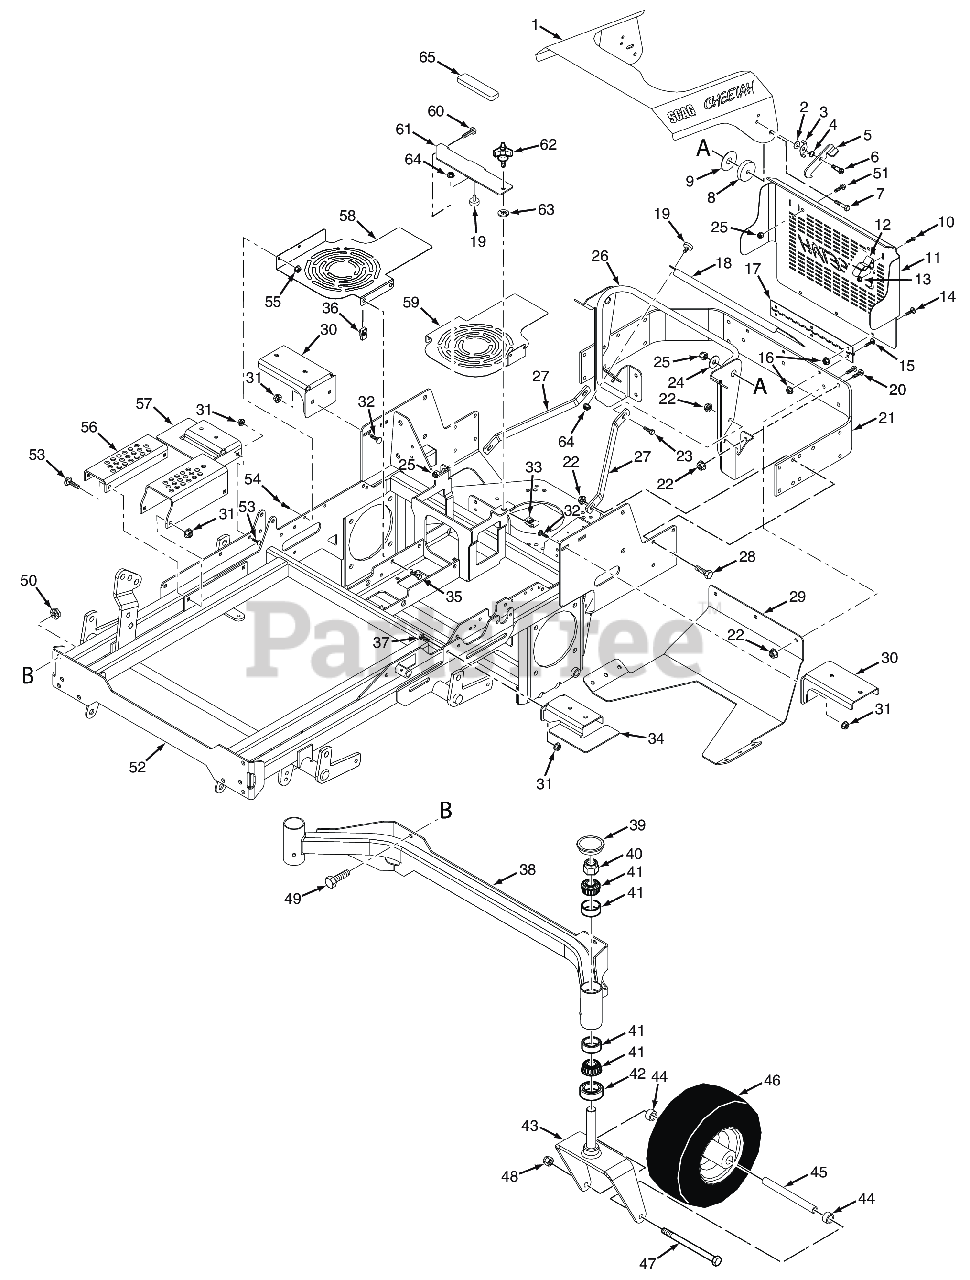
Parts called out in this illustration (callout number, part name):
1	Hood Assembly w/Decals
1	Hood Assembly w/Decals - Kohler ECV860
1	REPLACED BY 462721
2	Flatwasher, 3/8 (.406 x .812 x .065)
3	Lock, Hood Latch
4	Spring, Hood Latch
5	Latch, Hood
6	Bolt, Shoulder 5/16-18 x 1/2"
7	Bolt, Hex Head 3/8-16 x 1-3/4" (Kohler EFI)
8	Spacer, Hood
9	Disc, Anti-Friction
10	Screw, #8-32 x 1/2"
11	Belt Guard, Rear
11	Belt Guard, Rear - Kohler
12	Spring Clip
13	Nut, Elastic Stop #8-32
14	Bolt, Carriage 1/4-20 x 1/2"
15	Serr. Fl. Hex Head CPSCR, 1/4-20 x 3/4"
16	NUT, 1/4-20 SERRATED FLANGE HEX HEAD
17	Hinge, Belt Cover
18	ROPS Heatshield - Kohler
18	ROPS Heatshield - Briggs & Stratton
19	Bumper, Rubber 5/16-18 x 5/8"
20	Button Head Capscrew, Torx 3/8-16 x 1"
21	BUMPER, REAR - SCZ
22	NUT, 3/8-16 SERRATED FLANGE HEX HEAD
23	Bolt, Hex Head, 3/8-16 x 1 Gr. 5
24	Flatwasher, 3/8-.406 x 1-1-1/2 x 7 Gauge
25	HEX NUT, ELASTIC STOP LOCK, 3/8-16
26	Mount Weldment, Hood
26	Mount Weldment, Hood - Kohler
27	Brace, Hood Support
28	Bolt, Hex Head 3/8-16 x 1-1/4", Kawasaki FX / FS
29	SCZ Skid Plate, Kawasaki FX
29	SCZ Skid Plate, Kohler
30	Mounting Bracket, Fuel Tank Rear
31	Nut, Serrated Flange 5/16-18 (Right Front Engine Mounting, Briggs and Kohler Only)
32	Bolt, 5/16-18 x .75 RHSN Carriage
33	U-Nut, 3/8-16 (short)
34	Mounting Bracket, Fuel Tank Front
35	Capscrew, Hex Head 1/4-20 x 1"
36	Bolt, Hex Head 3/8-16 x 1"
37	Bolt, 5/16-18 x .75 RHSN Carriage
38	Caster Support Weldment, 61V
38	Caster Support Weldment, 72V
39	Cap, Grease
40	Nut, Hex Elastic Stop 1.0"-14
41	BEARING & CUP, TAPERED SPINDLE
42	Seal, 2.00" O.D. x 1.625" Bore
43	Yoke Weldment, Caster (61V & 72A/VS)
44	Spacer, Caster Wheel
45	Sleeve, Caster Wheel (61V, 72A/VS)
46	Wheel Assy, 61V, 72V (Incl. 20, 54, 55)
46	Bearing, Tapered Roller
46	Fitting, Grease
47	Bolt, Hex Head 1/2-13 x 9-1/2" (61V & 72A/VS)
48	HEX LOCKNUT, ELASTIC STOP, 1/2-13
49	BOLT, HEX HEAD, 7/16-14 X 1-1/4
50	Nut, 7/16-14 Flange Elastic Stop
51	Capscrew, Button Head 3/8-16 x 1-1/4"
52	Mainframe Assy. w/Decals
53	Bolt, Heax Head 5/16-18 x 1" (48V / 52V)
53	Lockwasher, 5/16 (.317 x .586 x .078) Helical Spring
54	BOLT, HEX HEAD, 1/4-20 X 3/4 GR.5
55	NUT, 1/4-20 SERRATED FLANGE HEX HEAD
56	Adjustment Bracket, Lower Cut Height
57	Adjustment Bracket, Upper Cut Height
58	Fan Cover, RH
59	Fan Cover, LH
60	Bolt, Hex Head, 3/8-16 x 1 Gr. 5
61	Cover, Battery Box
62	Knob, w/stud 3/8-16 x 1-1/4"
63	Nut, Push-On - 3/8" Dia.
64	Nut, Serrated Flange 5/16-18 (Right Front Engine Mounting, Briggs and Kohler Only)
65	PAD, BATTERY SUPPORT
